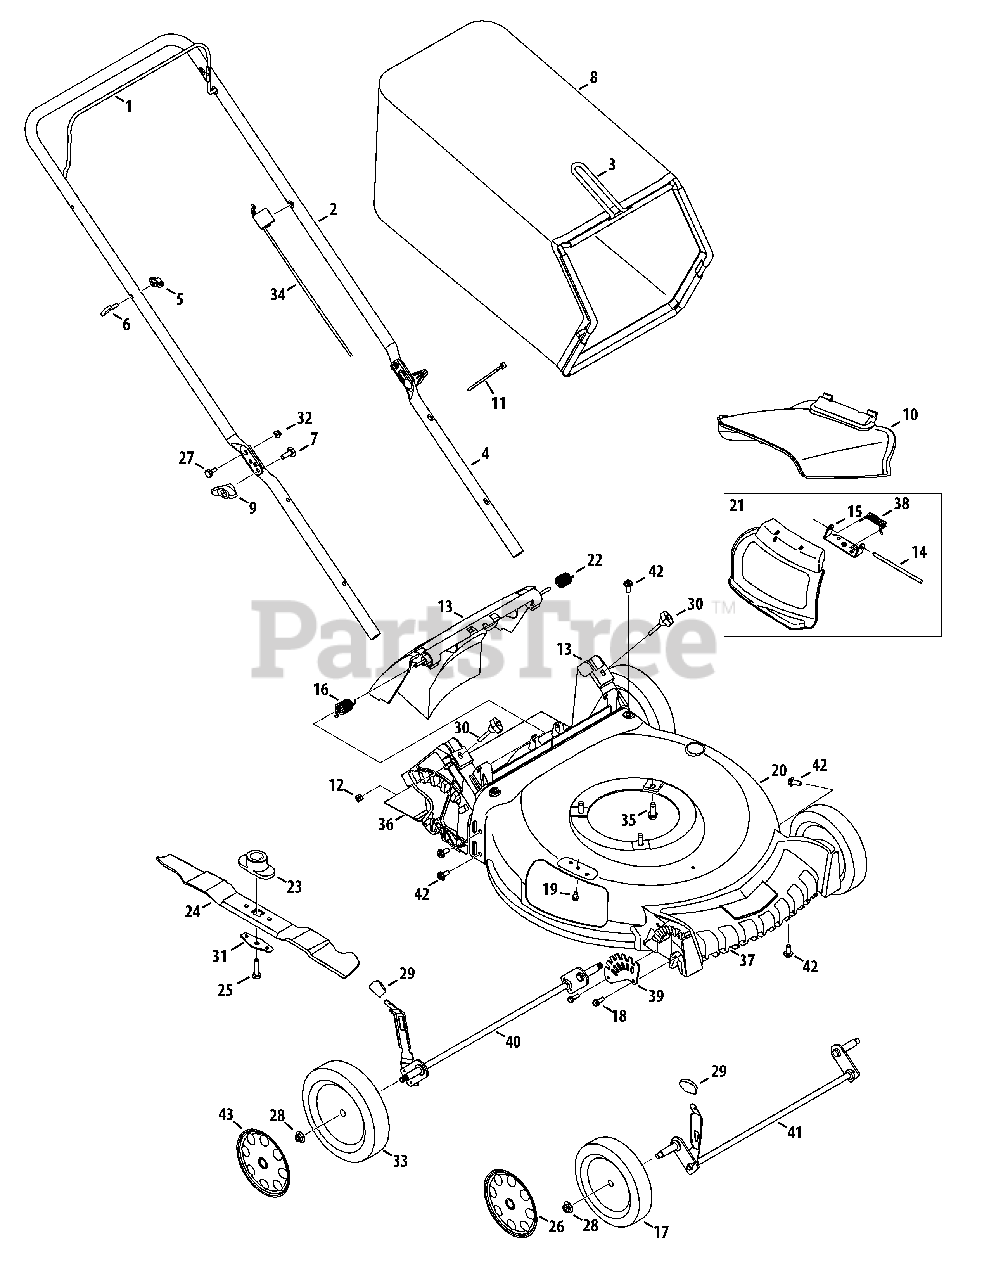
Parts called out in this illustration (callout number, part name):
1	Blade Control
2	Upper Handle
4	Lower Handle
6	Rope Guide
7	Carriage Screw ,5/16-18
8	Grass Bag
10	Side Chute
11	Cable Tie
12	Nut, Sq., 1/4-20
13	Rear Discharge Door Assembly (Lowes model)
13	Rear Discharge Door Assembly
15	Chute Deflector Bracket
16	Torsion Spring - RH
17	Front Wheel
18	Screw, 1/4-15 x .750
19	Screw, 1/4-20 x .500
20	Deck , 21"
21	Hinged Mulch Plug Assembly
22	Torsion Spring - LH
23	Blade Adapter
24	Mulching Blade
25	Screw , 3/8-24 x 1.50
26	Hub Cap, 7"
27	Sldr. Screw, .375 x .126 x 1/4-20
28	Flange Lock Nut, 3/8-16
29	Adjustment Lever Knob
30	Wing Nut
31	Blade Bell Support
32	Nut, Flange Lock, 1/4-20
33	Rear Wheel
34	Control Cable
35	TT Sems Screw, 3/8-16 x 1.0
36	Trail Shield
37	Front Cover
38	Torsion Spring
39	Front Height Adjuster Plate
40	Rear Axle Assembly
41	Front Axle Assembly
42	Screw, 5/16-14 x .750
43	Hub Cap, 8"
